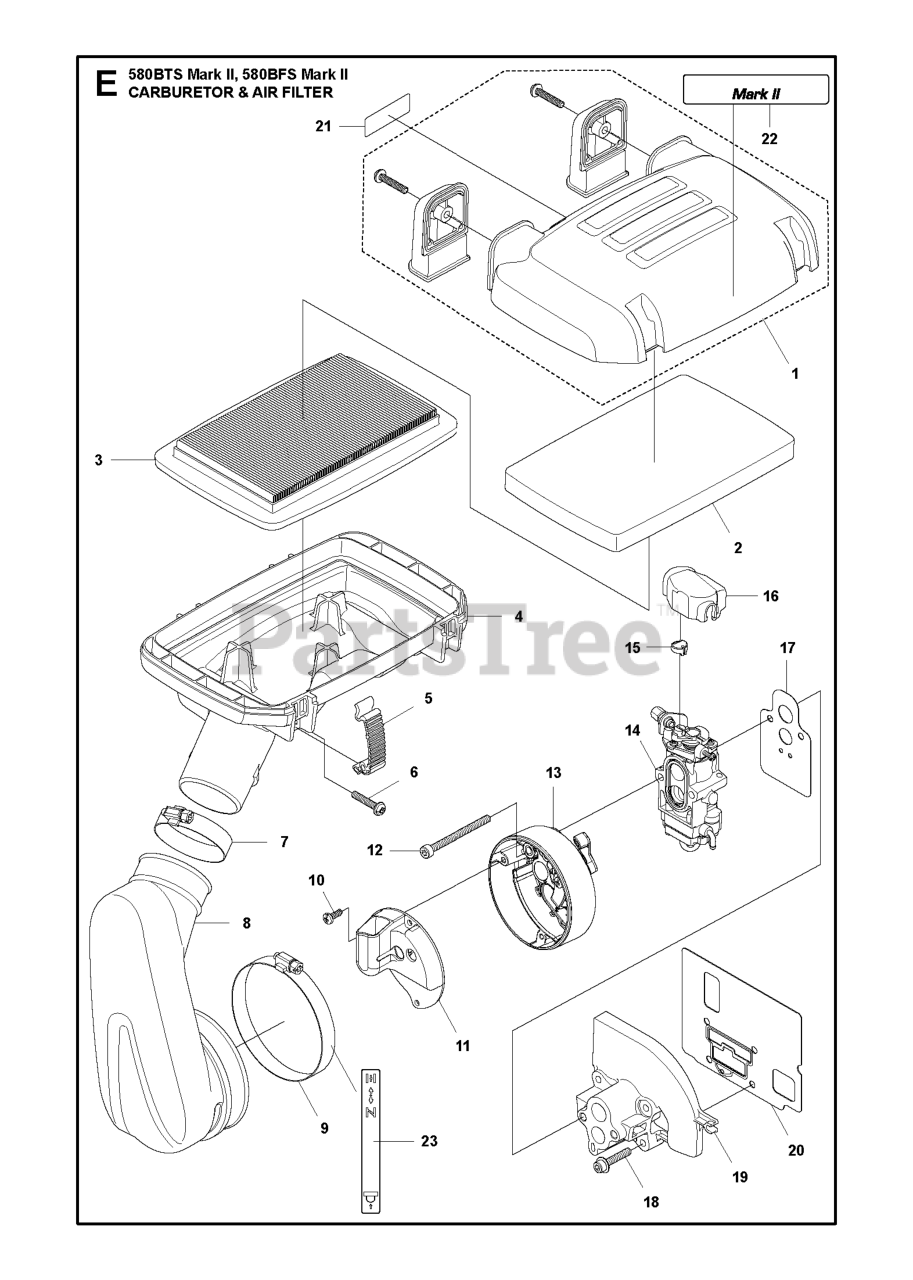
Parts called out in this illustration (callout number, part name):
1	AIR FILTER COVER ASSY
2	ELEMENT
3	ELEMENT
4	HOLDER AIR FILTER
5	BUCKLE ORANGE
7	CLAMP(F64)
9	CLAMP(F96)
14	CARBURETOR ASSY
15	CAP, CABLE END
22	DECAL CLEANER
